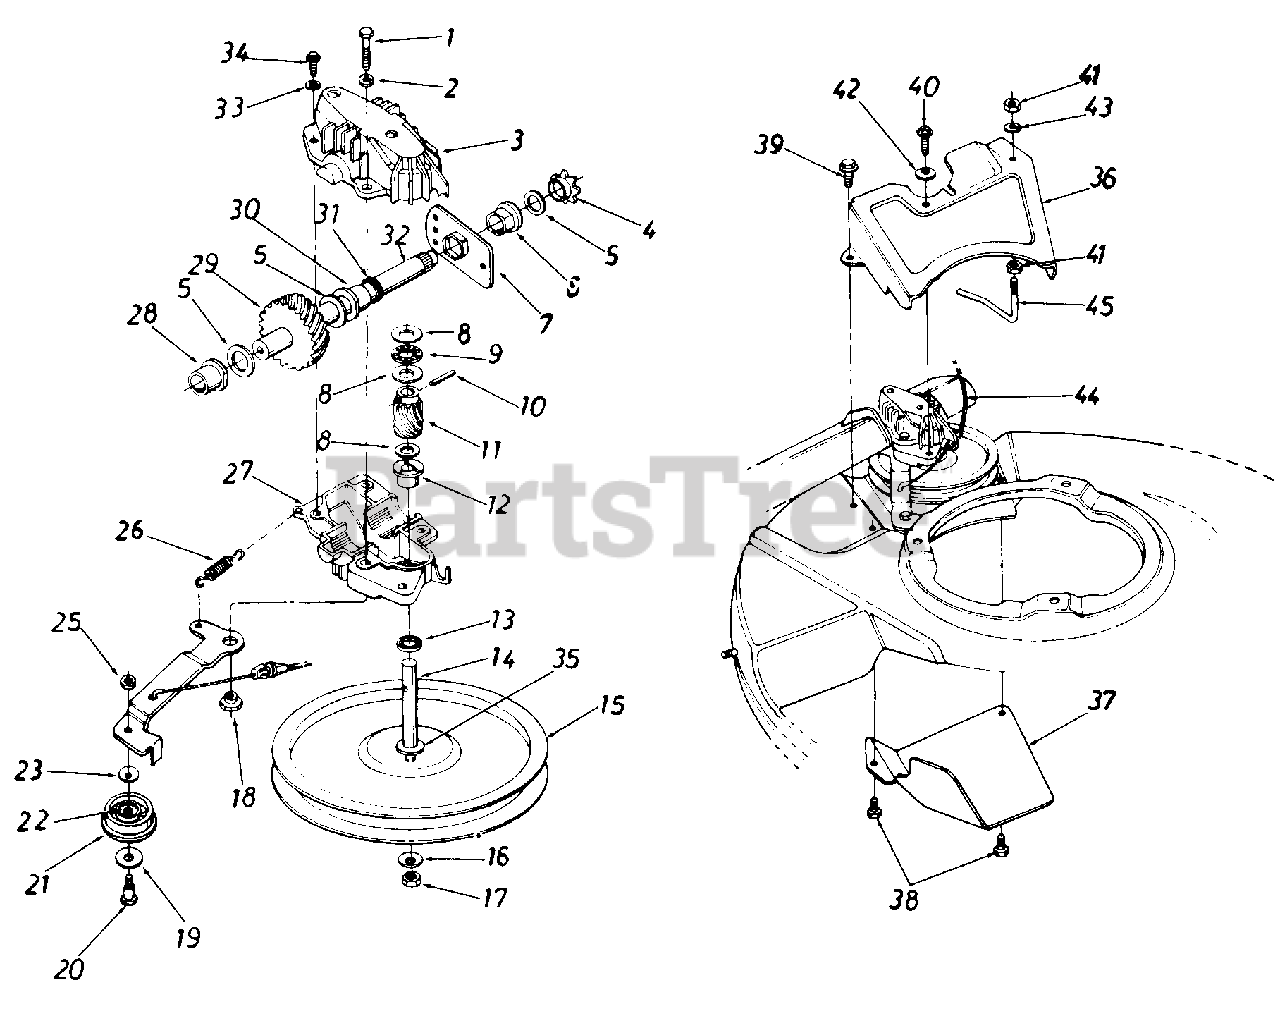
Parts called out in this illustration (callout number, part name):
1	Hex Bolt 1/4-20 x 1.25" Lg.*
2	L-Wash. 1/4" I.D.*
3	Upper Hsg. Half
4	#48 Sprocket 7 Tooth x 1/2 Pitch
5	Fl-Wash. 5/8" I.D. x .030
6	Hex Flange Brg. .631" I.D.
7	Hex Bearing Cup
8	Thrust Wash. .382" I.D. x .70" O.D.
9	Thrust Bearing .375" I.D. x .812" O.D.
10	Spring Pin Spir. 1/8" x .62" Heavy
11	11 Tooth Helical Gear
12	Flange Bearing
13	Oil Seal
14	Pulley-Transmission Shaft
15	Fl-Pulley 5.06" O.D.
16	Bell-Wash. .265" I.D. x .75"
17	Hex L-Nut 1/4-28 Thd.
18	Shld. Spacer .375" Dia. x .170
19	Fl-Wash. .390" I.D. x 1.0"
20	Shld. Bolt .375" Dia. x .40"
21	Fl-Idler Plastic 1.50" Dia
22	Needle Brg. .375" x .31
23	Bell-Wash. .265" I.D. x .75"
25	Hex Patch L-Nut 1/4-28 Thd.
26	Extension Spring 1.12" Lg.
27	Lower Hsg. Half
28	Flange Bearing .566 Dia.
29	33 Tooth Helical Gear
30	Flange Bearing .629 Dia.
31	Oil Seal .625 Dia.
32	Gear Sprocket Shaft
33	L-Wash. #10 I.D.
34	Hex B-Tap Scr. #10 x .62"
35	Hex Washer .26" x .88"
36	Transmission Belt Guard
39	Hex AB-Tap Scr. 1/4 x .50" Lg.
40	Hex B-Tap Scr 1/4 x 62" Lg
41	Hex Nut 1/4-20 Thd.*
42	Bell-Wash. .265" I.D. x .75"
43	L-Wash. 1/4" I.D.*
44	S.P. Cable-50" Lg.
45	S.P. Belt Guard
